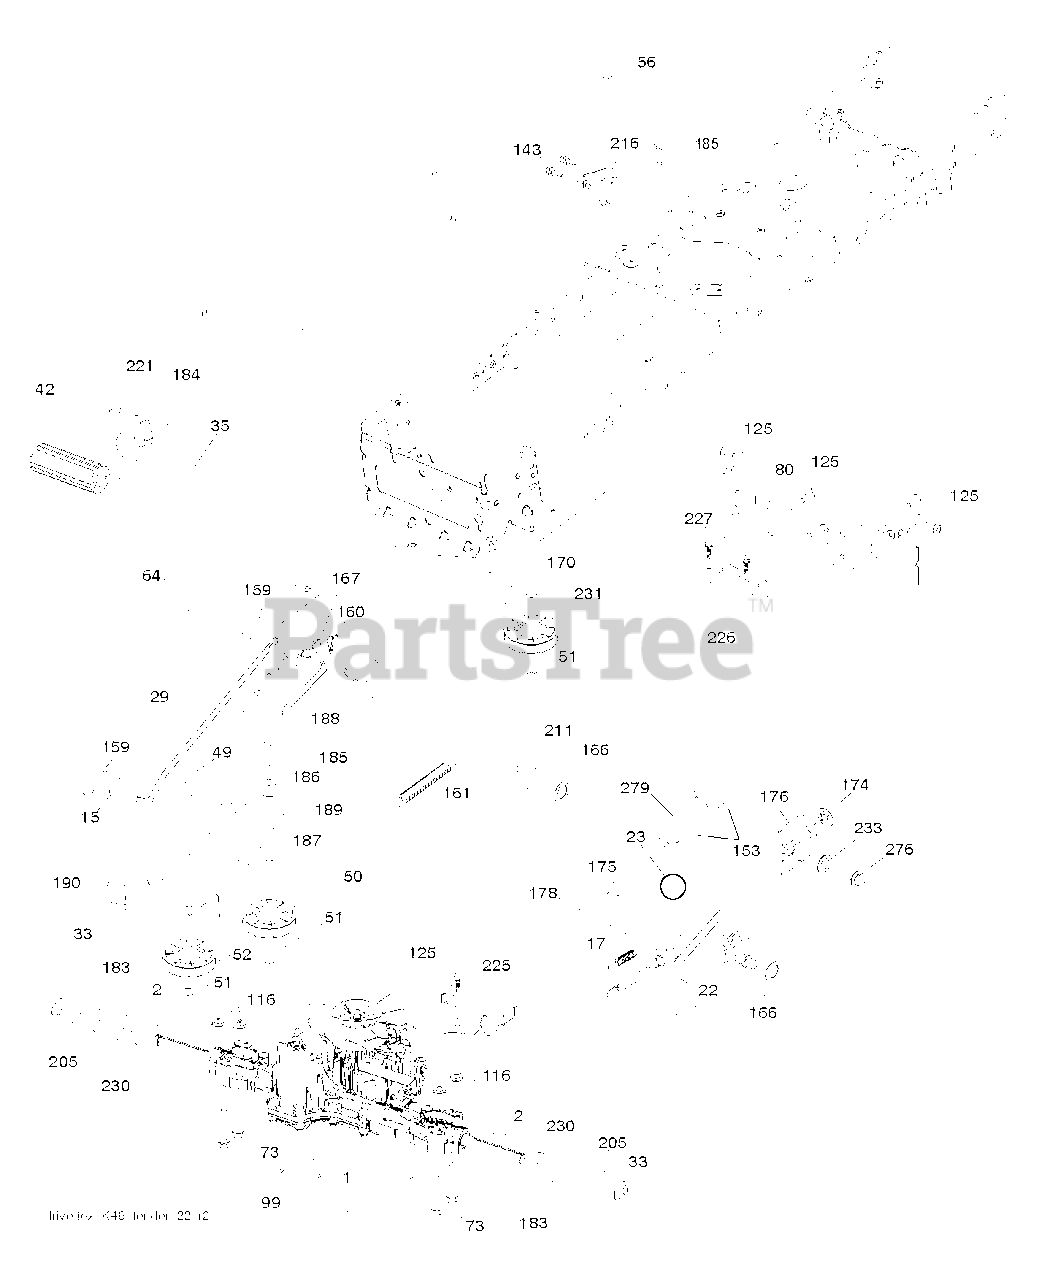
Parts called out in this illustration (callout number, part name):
2	SQUARE KEY
15	WASHER
17	SPRING.BRAKE.K46.GREEN
23	KNOB.DUCKHEAD.1/2
29	ROD.BRAKE.K46
35	ROD.CNTRL.PARK.PREDATOR.LT.TEX
42	PEDAL COVER T
50	IDLER.FLAT.910.OFFSET
51	NUT LOCK FLG 3/8-16 UNC
52	IDLER.V-GROOVE.910.OFFSET
56	V-BELT.MOWER.92.40.42/K46
64	SHAFT.ASM.PEDAL.BRAKE.
80	STRAP.TORQUE.K46.K57R.TT
99	ROD.SPRING.BYPASS.K46.LT.Z
116	NUT LOCK HEX FLANGE 5/16-18
125	SCREW
143	SCREW LT
153	RETAINER M
159	COTTER PIN
160	RETAINER CLIP
161	SPRING, RETURN LT
166	NUT.PUSH.625
167	LATCH.BRAKE.SPRING
170	KEEPER.CENTER SPAN.1.688
174	NUT.PUSH.500.2006
175	SHAFT.ASM.SHFT.T2.TLT
176	ARM.CLEVIS.ROD.SHIFT
178	SPRING.SHIFT.GT2006
183	SPACER AXLE
184	HANDLE.PARKING.BRK.PRED.LT.RED
186	SPACER.RETAINER
187	WASHER 12/32X2X10GA
188	RP LINK.CLUTCH.GROUND.DRIVE
189	BELLCRANK.GROUND.DRIVE.TEX.
190	KEEPER.BELLCRANK.DRIVE
211	BUSHING.SHAFT.BRAKE.HAND
216	BRACKET.PULLEY.IDLER.W/TEX
221	RETAINER.SPRING.CLIP.H
225	KEEPER.BELT.TRANSAXLE.K46
226	BRACKET.MOUNT.TORQUE.K46.TLT
227	SCREW
230	WASHER.HARDENED
231	IDLER.V-GROOVE.1.688.OFFSET
233	WASHER SERRATED
276	BOLT FIN HEX 7/16-14 X 1
279	LINK.SHIFT.
